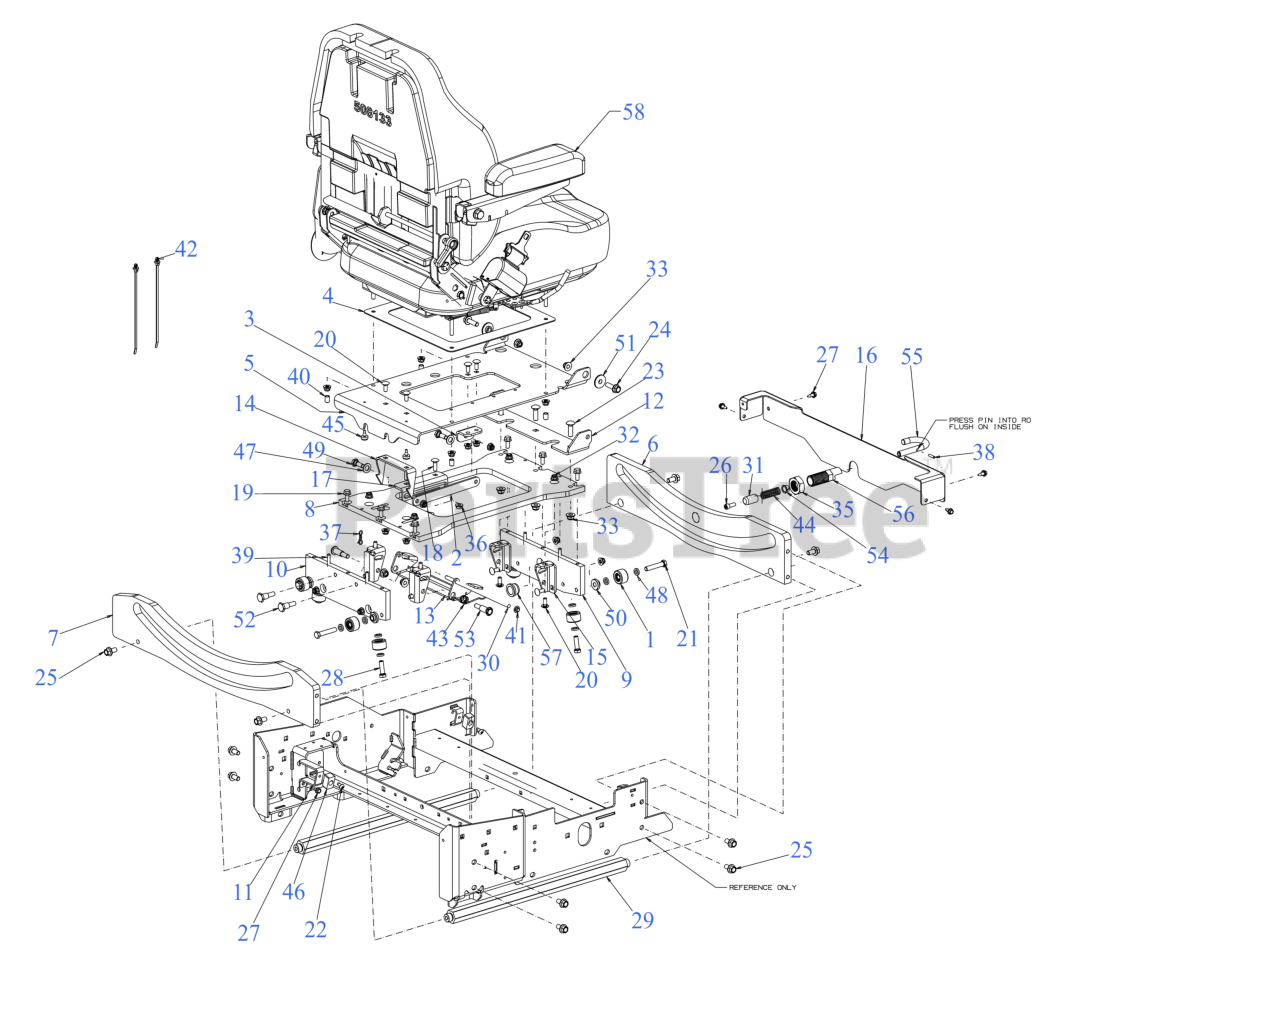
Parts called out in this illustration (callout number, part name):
2	SEAT LOCKOUT BRACKET
5	SEAT MOUNT PLATE
6	FRONT PLATE
7	REAR PLATE
8	TOP CARRIER PLAT
9	FRONT CARRIER PLATE
10	REAR CARRIER PLATE
11	BUMPER MOUNT BRACKET
12	SEAT PIVOT BRACKET
13	SEAT LATCH BRACKET
14	SEAT LATCH BRACKET
15	CARRIER PLATE GUSSET
16	FRONT TOP COVER
17	SEAT MOUNT LOCKOUT
18	CARRIAGE BOLT 5/16-18 x 1.00
19	SCREW 5/16-18
20	CARRIAGE BOLT 5/16-18 x .75
21	SCREW 3/8-16 x 2.00 GR5
22	SCREW 1/4-20 x .5
23	CARRIAGE BOLT 3/8-16 X1.25 GR5
24	SCREW 3/8-16 x 1.25 GR5
25	BOLT - 3/8-16:.75:GR5:PATCH LOCK
26	SCREW 5/16-18 x .625
27	SCREW 1/4-20X.625
28	SCREW 3/8-16 x 1.25 GR5
30	SEAT LATCH SHAFT
32	PLUNGER LOCK SHAFT
32	FLANGE LOCK NUT 5/16-18
34	FLANGE NUT
35	JAM NUT 1-14 GR5
36	HEX FLANGE NUT
37	BOW TIE COTTER PIN 1/4-5/16
38	DOWEL PIN
42	CABLE TIE
43	TORSION SPRING
44	COMPRESSION SPRING .66 OD x 1
45	BUMPER, .62 DIA x .3
46	ROPS BUMPER
47	FLAT WASHER
48	FLAT WASHER
49	SHOULDER SCREW .437 DIA x .265
50	SHOULDER SPACER 1.00 x .38 x .38
51	SHOULDER SPACER
52	SHOULDER BOLT .50 DIA x .66
53	SHOULDER SCREW .50X.925
54	NYLINER BEARING
56	HUB MT LOCK
57	SHOULDER SLEEVE
58	SEAT (ELEC LUMBAR)
58	ISO LEVER W/ROLL P
58	AIR COMPRESSOR HARNESS
58	TRACK KIT-7" HD SINGLE LOCK
58	BELLOWS-W/HARDWARE
58	AIR COMPRESSOR KIT
58	SET OF ARM PADS
58	SET OF FRONT ADJUST ARMS PADDED
58	SEAT KNOB KIT
58	2" RETRACTABLE BELT KIT
58	HOSE KIT WITH AIR VALVE
58	BACK COVER WITH LOGO
58	AIR VALVE PADDLE TYPE
58	SEAT SWITCH NC/NO
